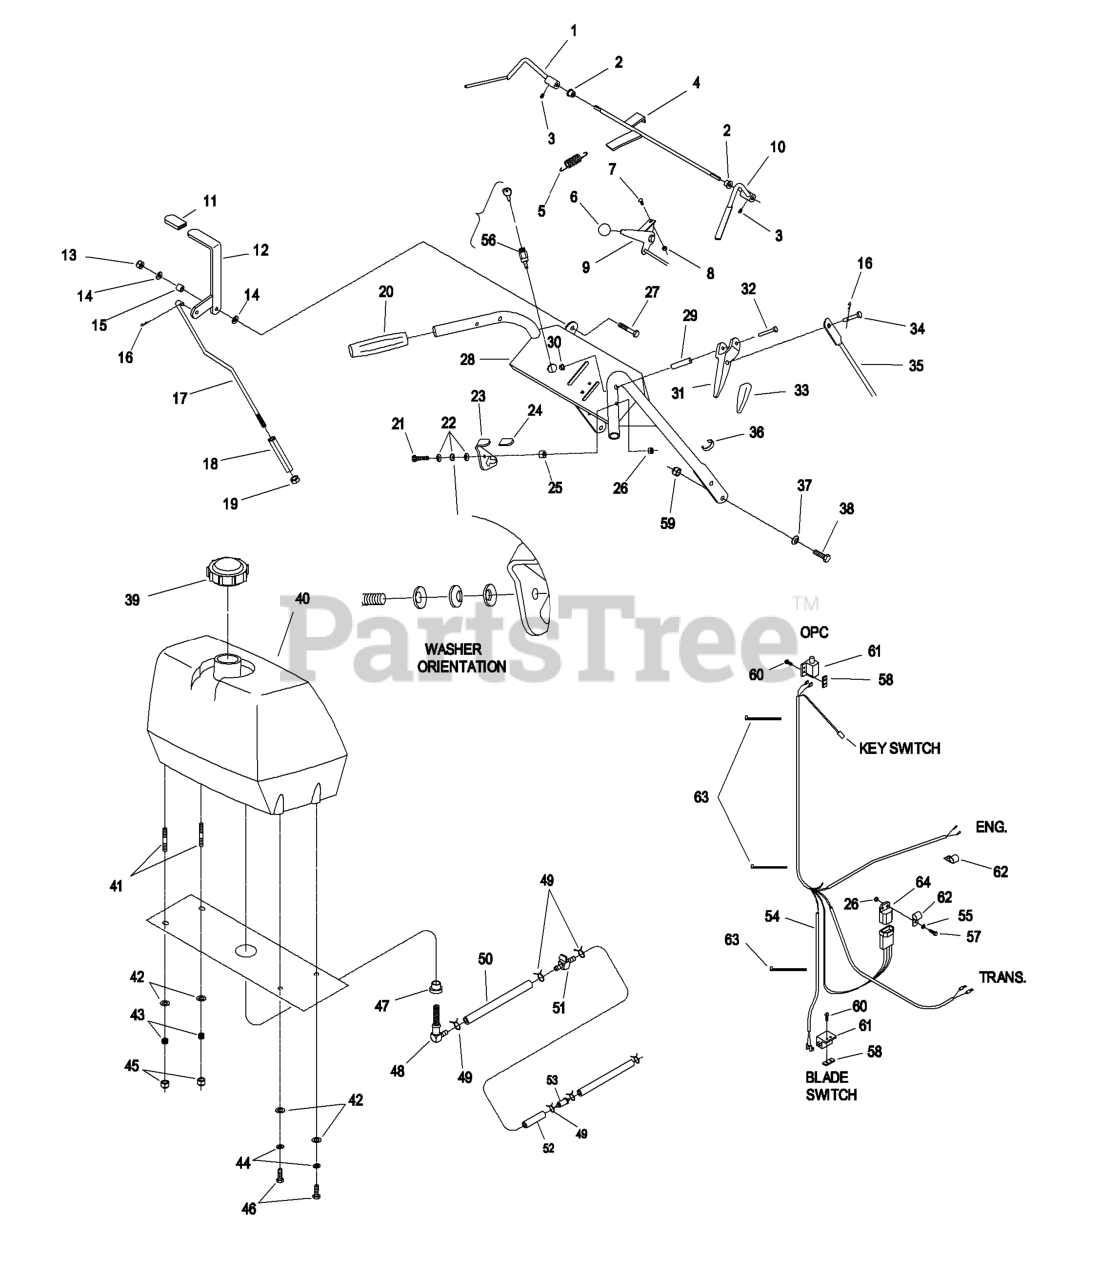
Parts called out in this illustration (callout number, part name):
1	LEVER-LH
2	BUSHING-NYLON
3	SCREW-SET
4	WLD,ROD OPC
5	SPRING-EXTENSION
6	KNOB-BALL
7	BOLT-CARR
8	NUT-LOCK, NI
9	CONTROL,THROTTLE
10	LEVER-RH
11	GRIP-LEVER
13	NUT-LOCK, NI
14	WASHER-FLAT
15	BUSHING-LEVER, LIFT
16	PIN-COTTER
17	LINKAGE,UPPER
18	TURNBUCKLE
19	NUT-HEX
21	SCREW-HH
22	WASHER-SPRING
24	GRIP-LATCH
26	NUT-LOCK, NI
27	SCREW-HH
28	KIT,HANDLE/DECALS MHP
29	PIN-ROLL
30	NUT-PUSH
31	DRIVE LEVER ASM
32	PIN-LEVER, DRIVE
33	GRIP-LEVER, DRIVE
34	PIN-CLEVIS
35	LINKAGE,DRIVE WHEEL
36	CLIP-CABLE
37	WASHER-BELLEVILLE
38	SCREW-HH
39	CAP-FUEL
41	STUD
42	WASHER-PLAIN
43	SPRING-TANK, FUEL
44	WASHER-LOCK
45	NUT-LOCK, NI
46	SCREW-HH
48	ELBOW-TANK, FUEL
50	HOSE-FUEL
51	VALVE-FUEL
52	HOSE-FUEL
53	Kawasaki Pn 41019-1055
55	WASHER-FLAT
56	SWITCH & KEY (INCLUDES NU
57	SCREW-HH
58	PLATE-TAPPED
59	NUT-HHF, WHIZ
60	SCREW-PPH
61	SWITCH-OPEN, NORMALLY
62	CLIP-LOOM
63	TIE-CABLE
64	MODULE-INTERLOCK
